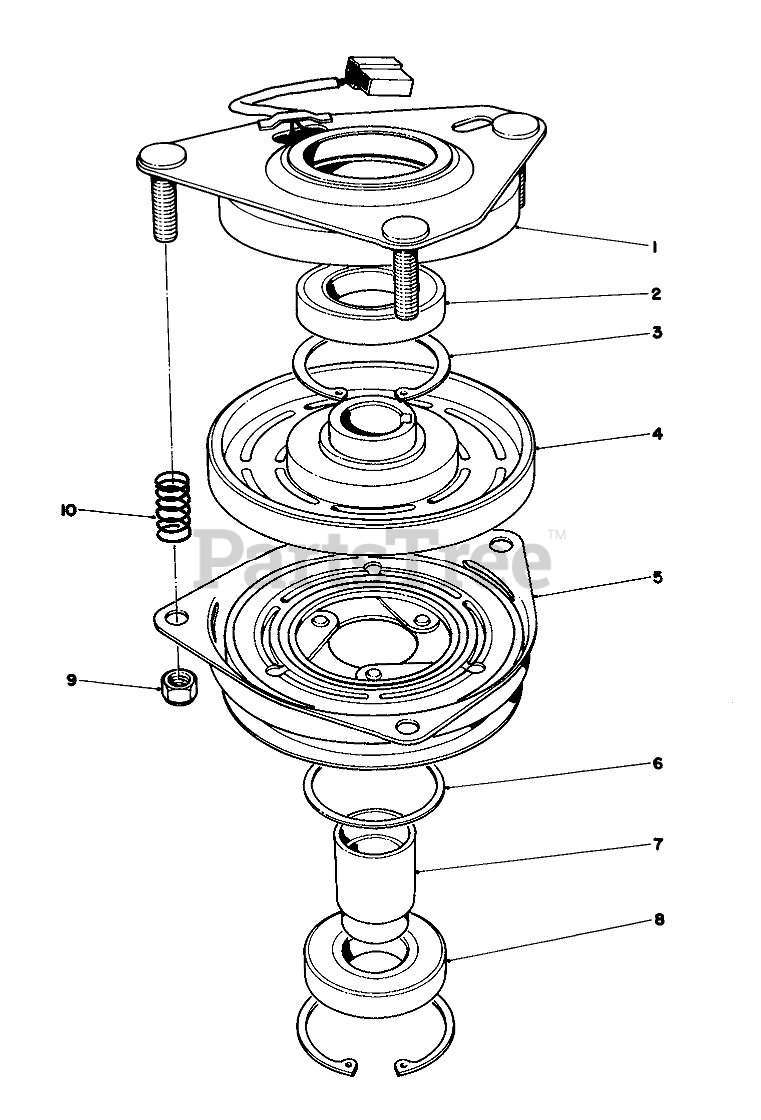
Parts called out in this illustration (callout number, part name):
1	Field Assembly (Incl. Ref. #2 & 3)
2	BEARING-FIELD
3	RING-RETAINING
4	Field Coil, Rotor & Bearing Assembly (Incl. Ref. #1)
5	Armature & Pulley Assembly (Incl. Ref. #3, 6, 7 & 8)
6	SPACER-BEARING, PULLEY
7	COLLAR-BEARING
8	BEARING-PULLEY
9	NUT-LOCK
10	SPRING
